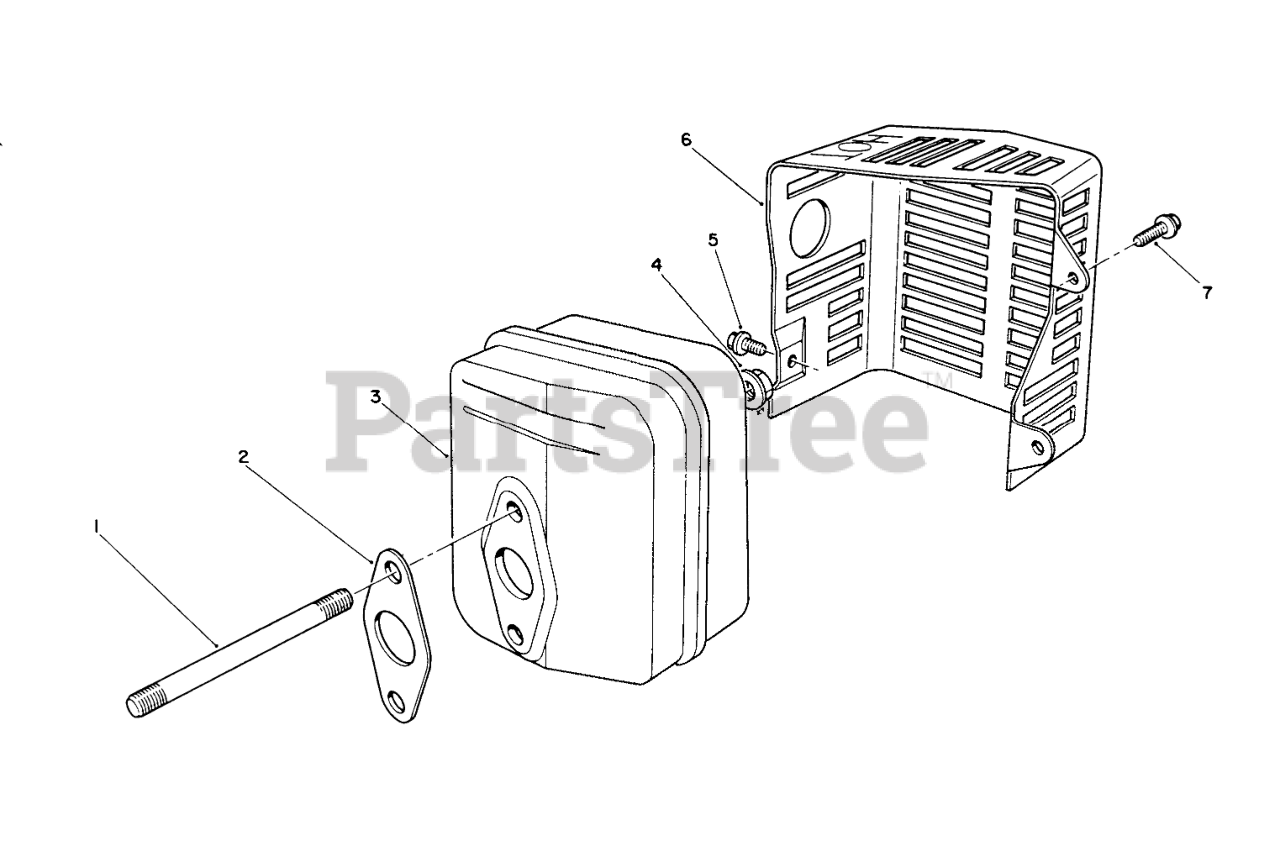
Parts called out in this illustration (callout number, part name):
2	GASKET
3	MUFFLER
5	SCREW
6	COVER
